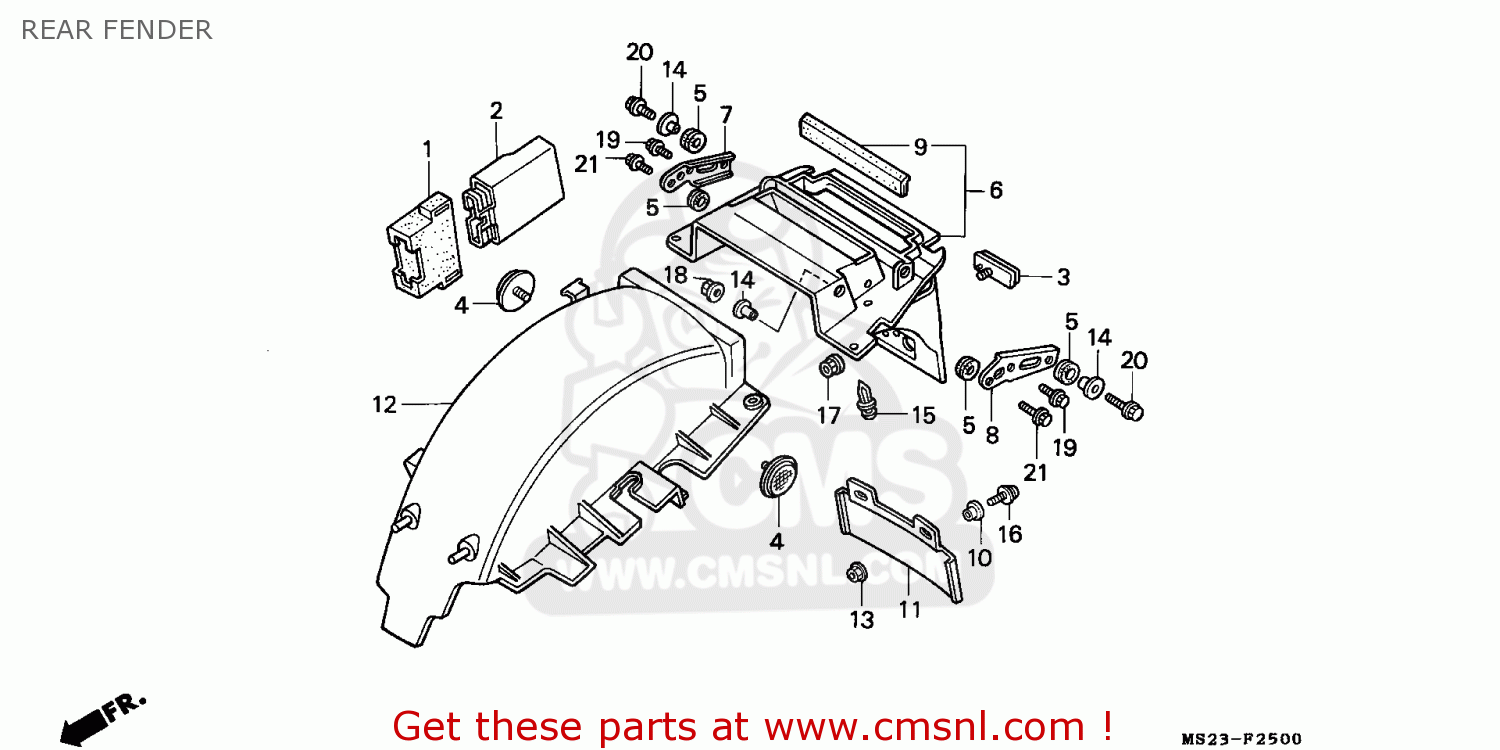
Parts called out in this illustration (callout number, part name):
1	CUSHION,SPARK UNI
2	SPARK UNIT
3	REFLECTOR,REFLEX
5	RUBB,LIGHT MOUNT
6	FENDER A,RR
7	STAY,R.RR.FENDER
8	STAY,L.RR.FENDER
9	RUBBER,FENDER SEA
12	FENDER COMP.(B)
14	COLLAR,6.2X12
15	CLIP,BODY COVER
17	NUT,FLANGE,5MM
21	BOLT,FLANGE,6X25
